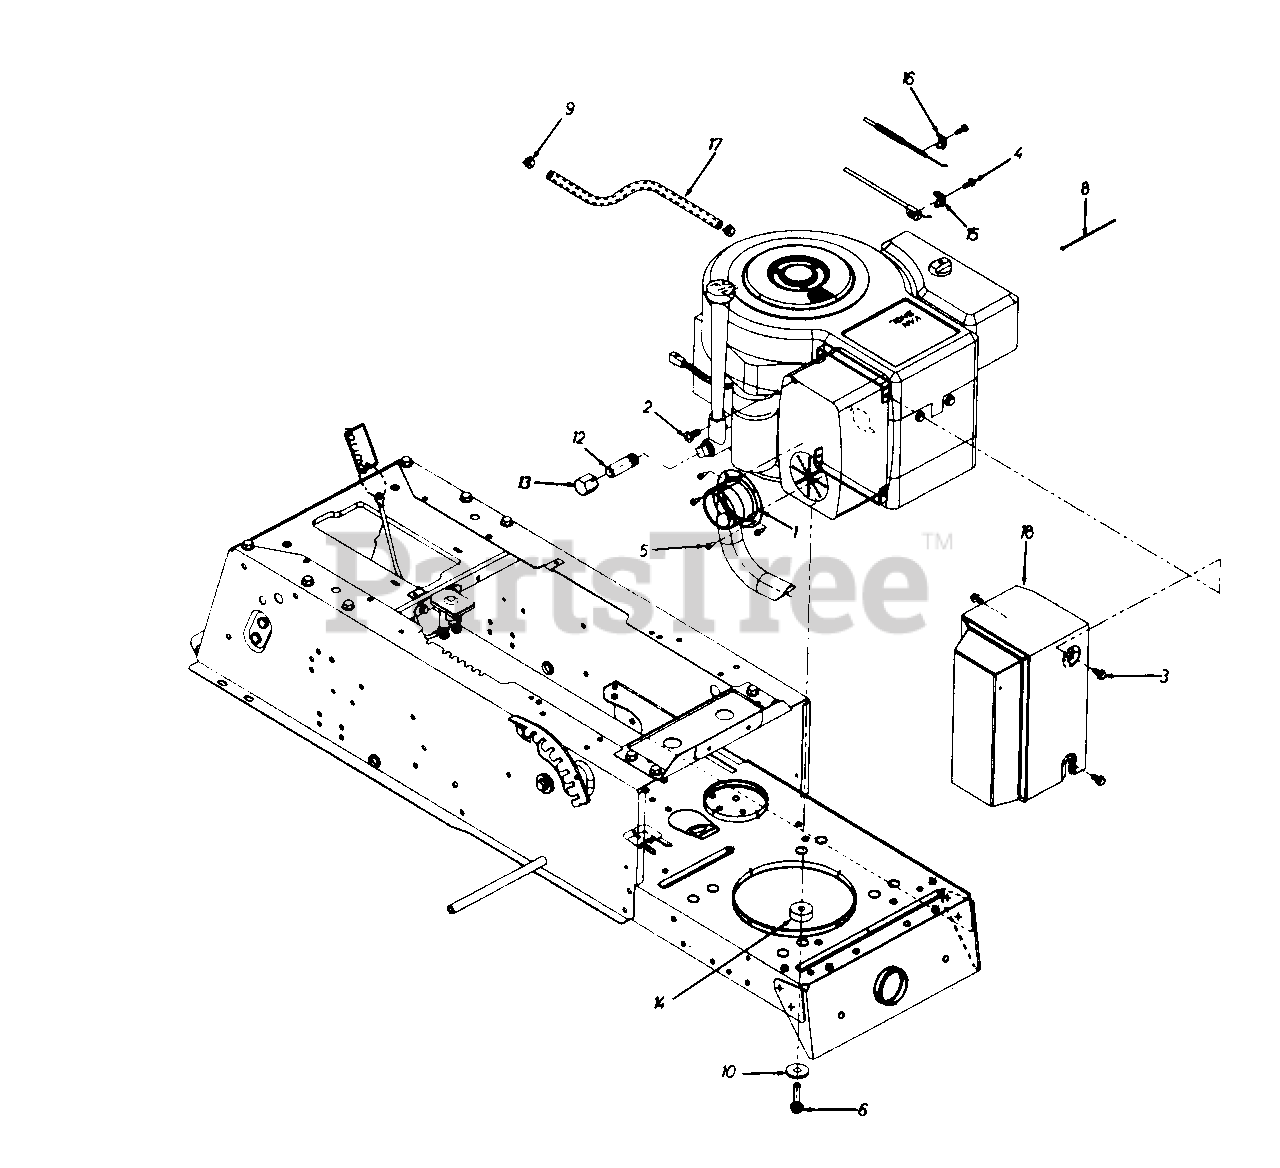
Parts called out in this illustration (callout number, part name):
1	Exhaust Pipe Ass'y.
2	Pan Hd. Mach. Scr. 5/16-18 x .75" Lg.
3	Hex Wash. Hd. Scr. 1/4 x 20 x .5" Lg.
4	Hex Wash. Hd. Scr. #10-32 x 5/8" Lg.
5	Hex Wash. Tap Scr. #8-32 x .38" Lg.
6	Hex L-Wash. TT-Tap Scr. 3/8-16 x 1.5" Lg.
10	Fl-Wash. 3/8" I.D. x 1.25" O.D.
12	Pipe Nipple 3/8-18 NPT
13	Oil Drain Cap
14	Shld. Spacer.38" I.D. x 1.25"
15	Casing Clamp
17	Fuel Line
18	Muffler Heat Shield Ass'y.
